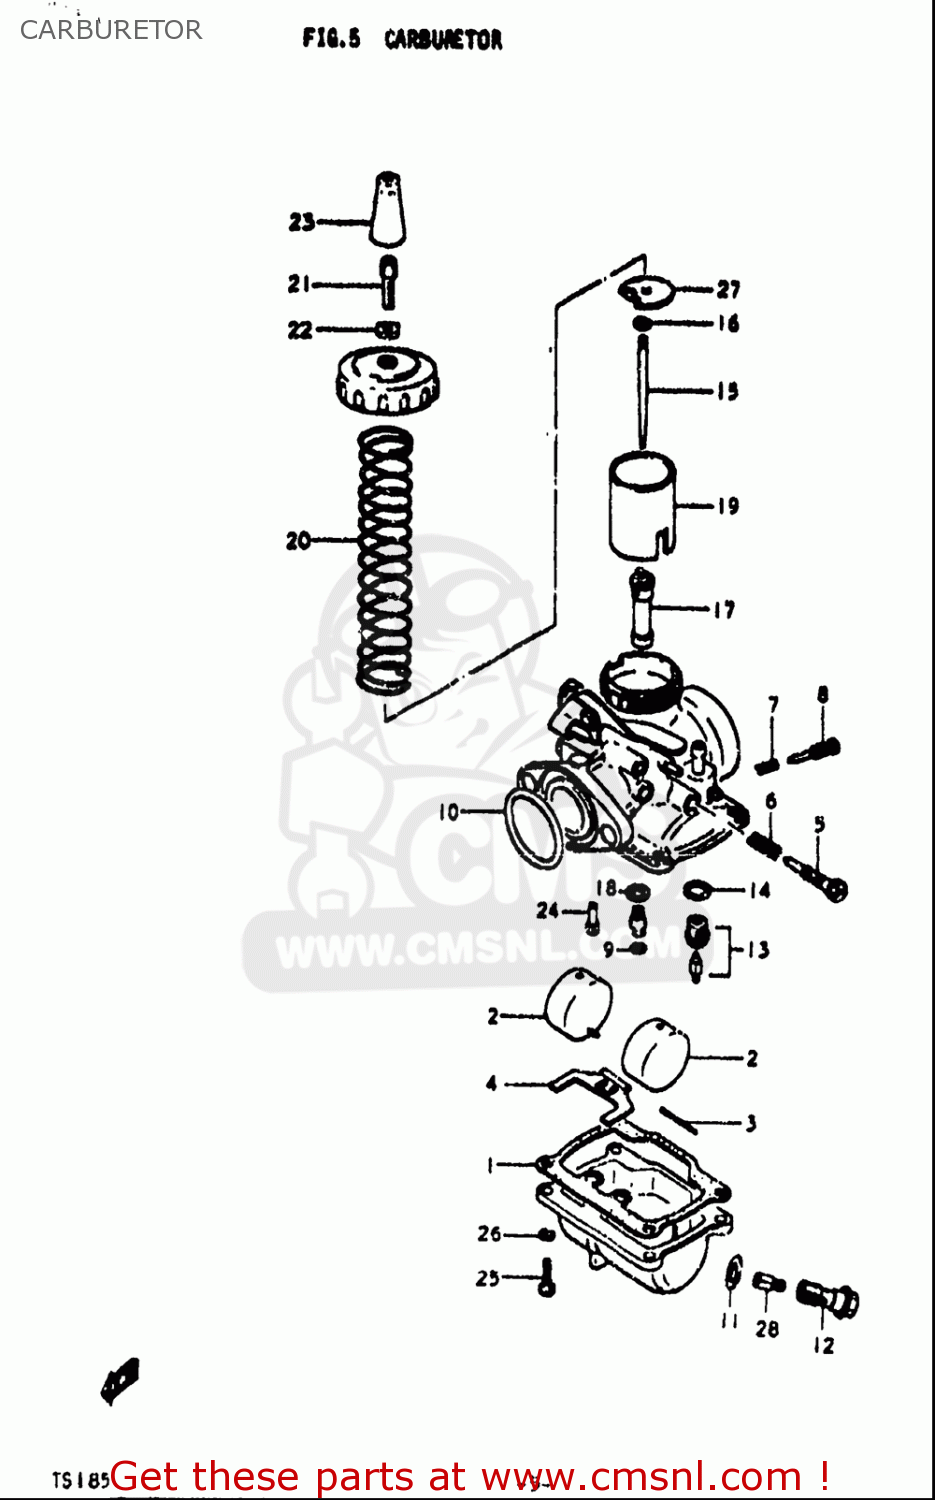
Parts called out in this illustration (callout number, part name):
1	GASKET,FLOAT CHAMBER (NAS)
2	FLOAT
3	PIN,FLOAT
5	SCREW,THROTTLE STOP
6	SPRING,THROTTLE SCREW
7	SPRING
8	SCREW,PILOT AIR
9	O RING
10	O RING
13	VALVE ASSY,NEEDLE
14	GASKET,VALVE SEAT (NAS)
16	CLIP,NEEDLE
18	WASHER
20	SPRING,THROTTLE VALVE
21	ADJUSTER,CABLE
22	NUT
23	CAP
24	JET,PILOT(25)
25	SCREW 4X16
26	WASHER,LOCK
27	SEAT,THROTTLE VALVE SPRING
28	JET,MAIN(130)
